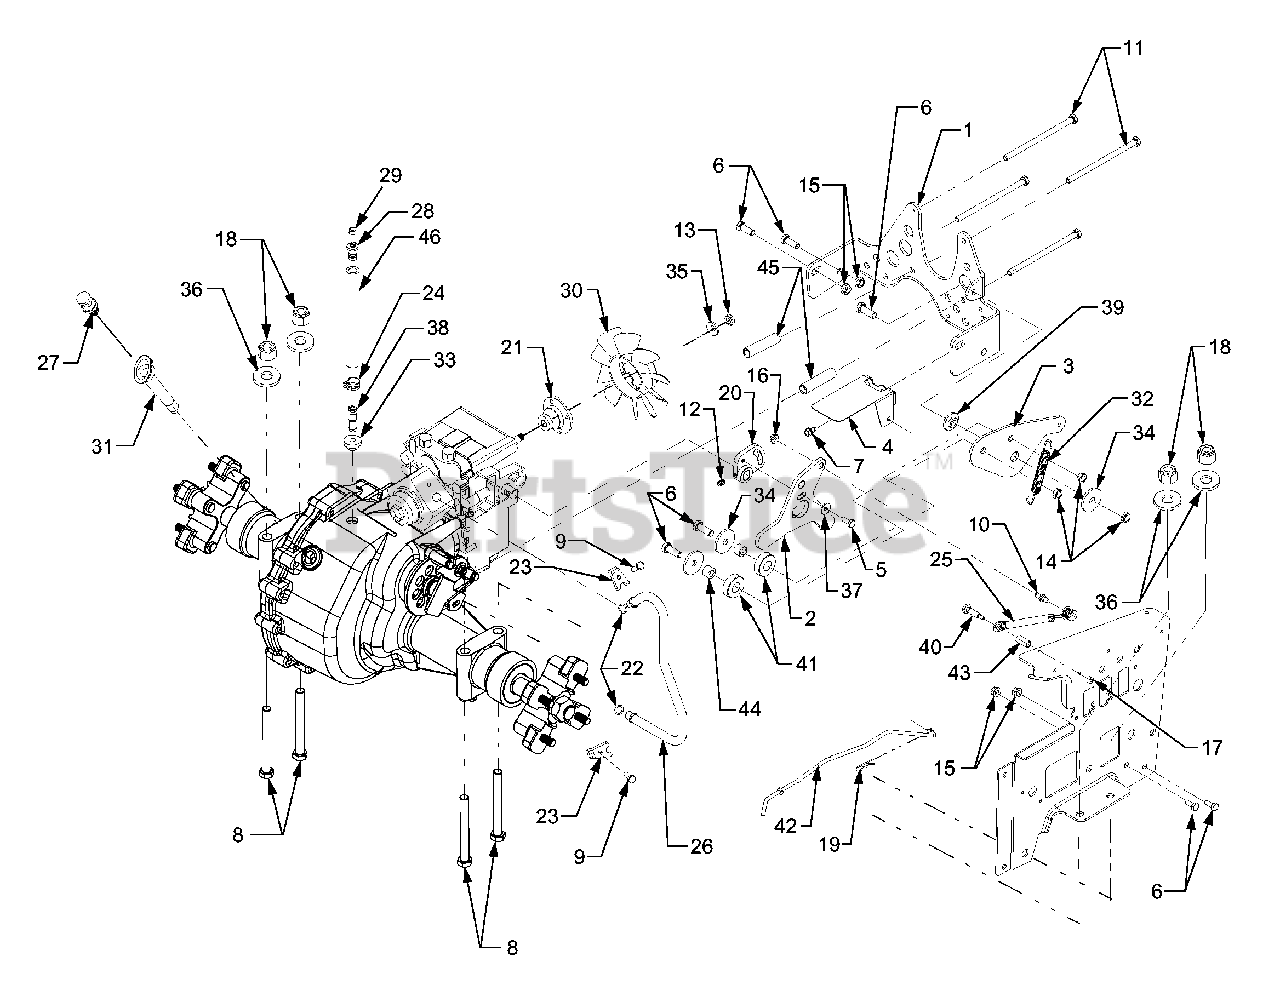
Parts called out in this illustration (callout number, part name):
1	Bracket, Torque
2	Plate, Hydro Neutral Return
3	Link, Neutral Return Bearing
5	Screw, Hex Cap, 1/4-20 x .625 GR5 Lock
6	Screw, Hex Cap, 3/8-16 x 1.0 GR5
7	Screw, Hex Wash. Hd. Tapp, 1/4-20 x .5
8	Screw, Hex Cap, 1/2-20 x 4.5 GR5
9	Screw, Hex Cap, 1/4-20 x .75 GR5
10	Ball Screw, 5/16-18 x .56
11	Screw, Hex Wash. Hd. Tapp, 5/16-18 x 5.5 GR5
12	Screw, Set, 5/16 x .5
13	Nut, Hex Top Lock Jam, 1/2-20
14	Nut, Hex Ctr. Lock Jam, 3/8-16
15	Nut, Hex Flange Lock, 3/8-16
16	Nut, Hex Flange Lock, 5/16-18
17	Nut, Hex, 1/4-20
18	Nut, Hex Insert Lock, 1/2-20
19	Pin, Internal Cotter
20	Arm, Hydro
21	Adapter, Pump
22	O-Ring, .426 ID x .566 OD x .070
23	Clamp, Tube
24	Clamp, Hose
25	Cylinder, Damper
26	Tube, Hydro Pickup
27	Dipstick, Transmission
28	Plastic Vent
30	Fan, Pump
31	Holder, Dipstick
32	Spring, Extension
34	Washer, Flat, .390 x 1.5 x .1
35	Washer, Bell, .5 x 1.0 x .05
36	Washer, Flat, .531 x 1.062 x .134
37	Washer, Flat, .26 x .72 x .06
38	Fitting, Tube
39	Spacer, Shoulder
40	Shoulder Bolt
41	Bearing, Ball
42	Rod, Pump Bypass
43	Spacer, .375 x .5 x 1.02
44	Spacer, .375 x .624 x .445
45	Spacer, Hydro, .3223 x .60 x 2.44
